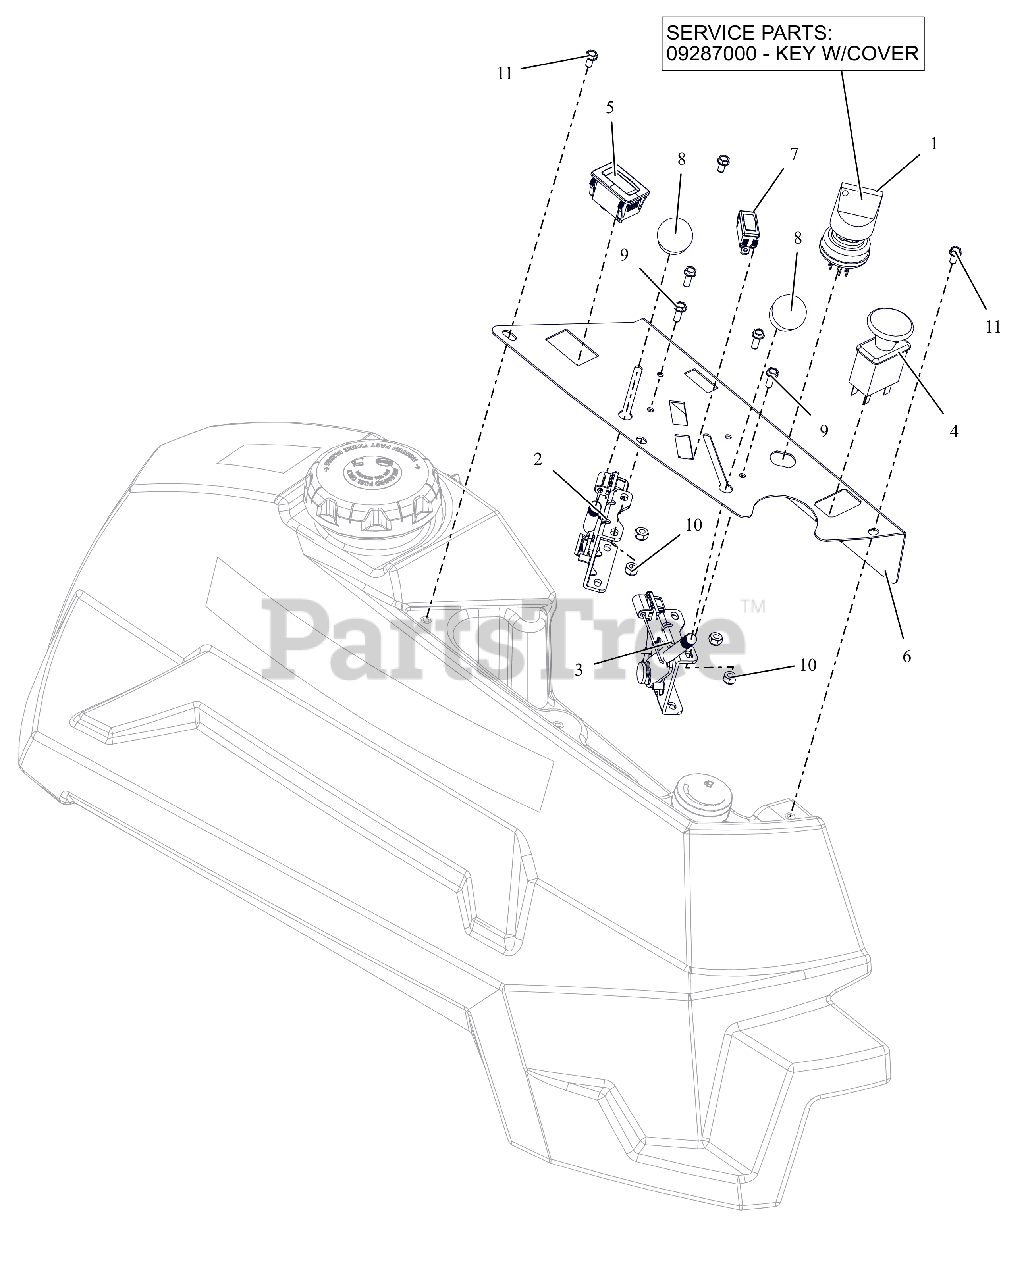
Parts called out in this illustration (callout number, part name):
1	SWITCH, IGNITION
1	KEY, W/ SHIELD
2	CABLE, PRO-CTRL 46.00"
3	CABLE, PRO-CTRL 53.00"
4	SWITCH, CLUTCH
5	HOUR METER
6	PT400 CONTROL PANEL - RED
7	LIGHT, INDICATOR (RED)
8	KNOB-CONTROL-BLACK .38-16X.50
9	BLT, HWH #10-24X.50 ZCC
10	NUT-LK-NYL #10-24 G2 ZCC
11	SCR-MCH 10-24X.38 HWHSTAINLESS
